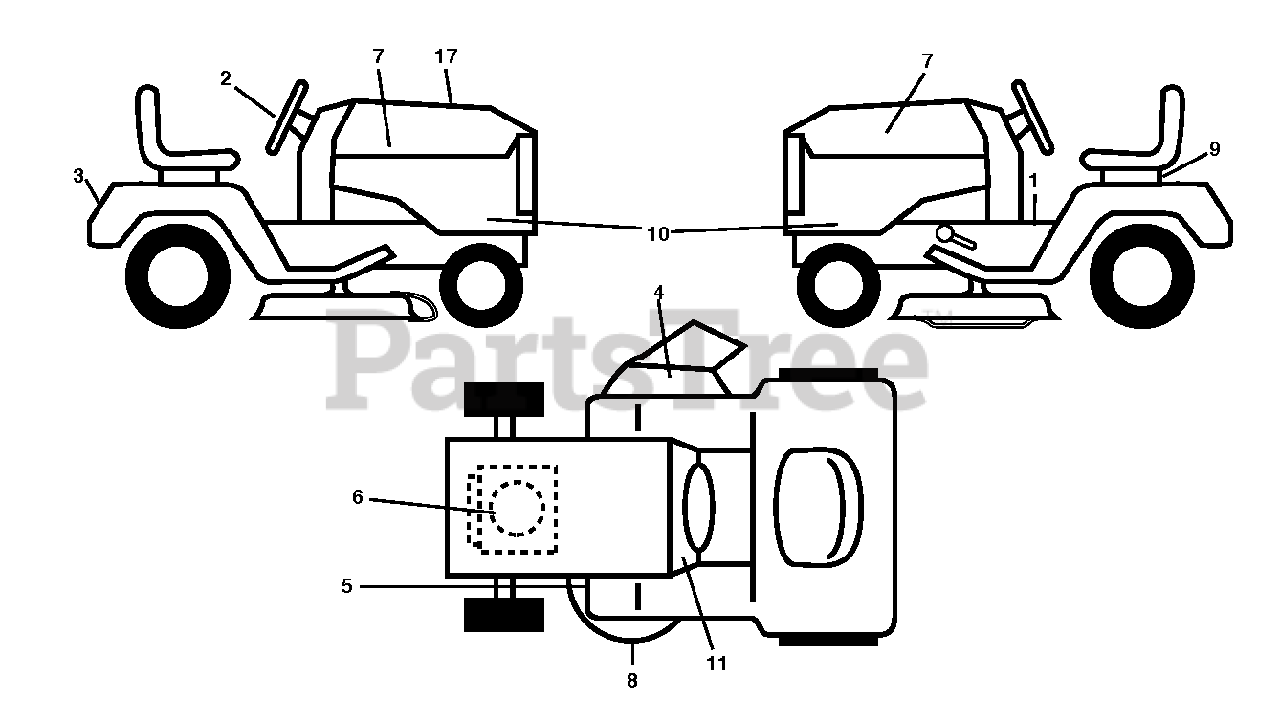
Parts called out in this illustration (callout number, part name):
1	DECAL.FENDER.WARNING.ENGLISH
2	Decal, Steering Wheel STDXXSQ PPRO 2015
3	DECAL.REARFNDR.POULAN PRO.2015
4	DECAL, DECK DEFLECTOR, WARNING
5	DECAL.V-BELT.SCH.42/46"MEC/ELE
6	Decal, Engine BSM33 INTEK 19HP RS
7	DECAL.POULAN PRO.2015
8	DECAL.PPRO.10YRDECKWAR.POP
9	DECAL BTRY SYMBOLS
10	DECAL TRACTOR SIDE PANEL DECAL
11	DECAL.DASH.SNOWFLAKE.BLACK.SM
17	Decal, Replacement BSM33 INTK TLW 46C K
